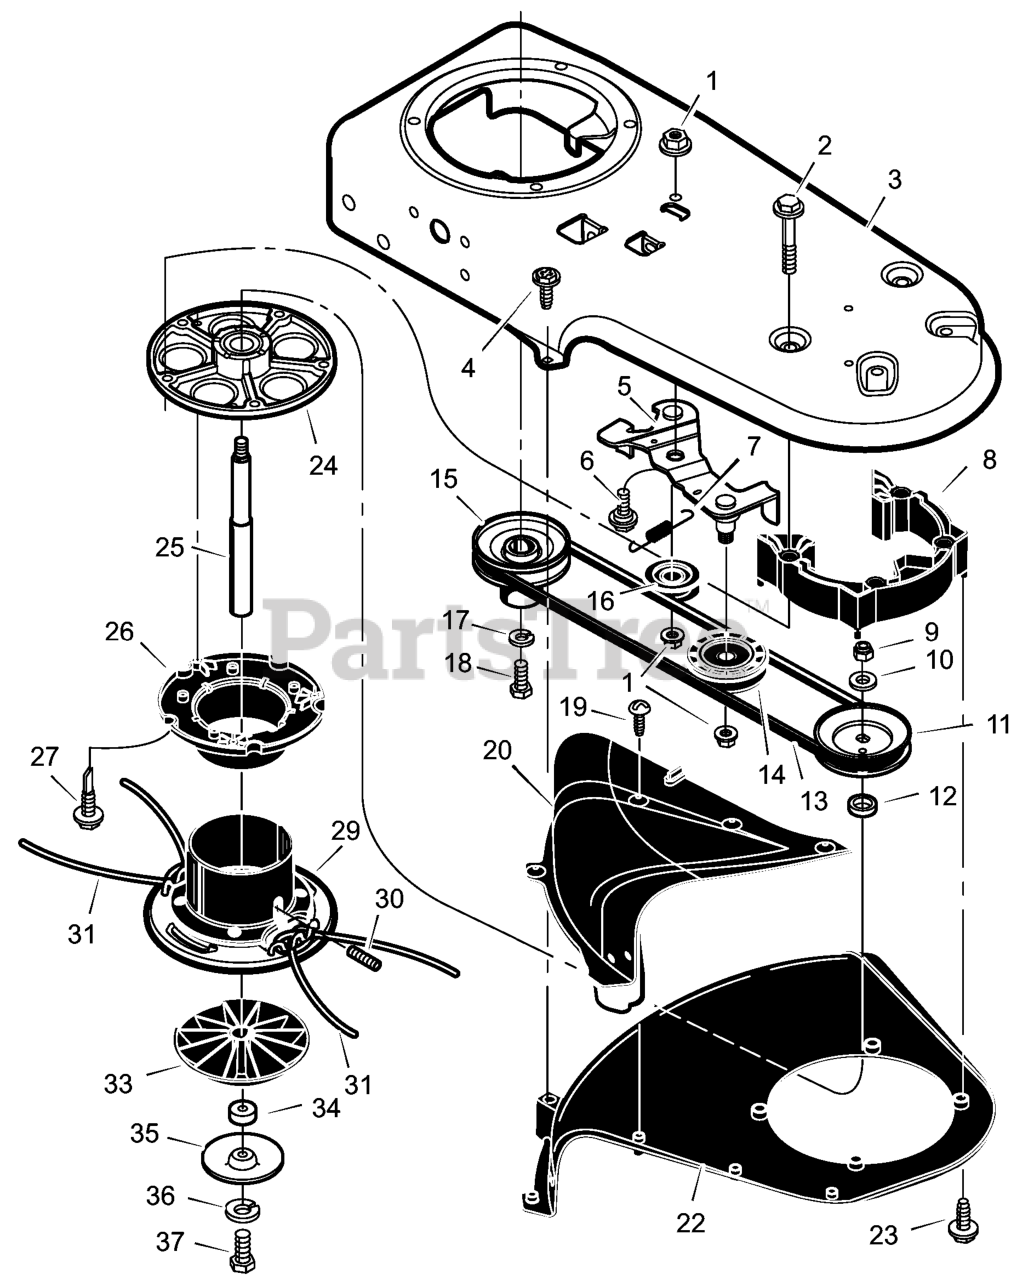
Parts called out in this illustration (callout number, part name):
5	Idler Assembly
11	PULLEY, Cutting Head
14	PULLEY, Idler
15	PULLEY, Engine
16	PULLEY, Idler
17	LOCKWASHER
20	GUARD Assembly
24	JACKSHAFT HOUSING ASSEMBLY
25	JACKSHAFT
26	WRAP, Upper Head
29	ASSEMBLY, Cutting Disc
30	SCREW, Set
31	LINE, Cutting
33	GUIDE, Height
35	SHIELD, Abrasion
36	LOCKWASHER
